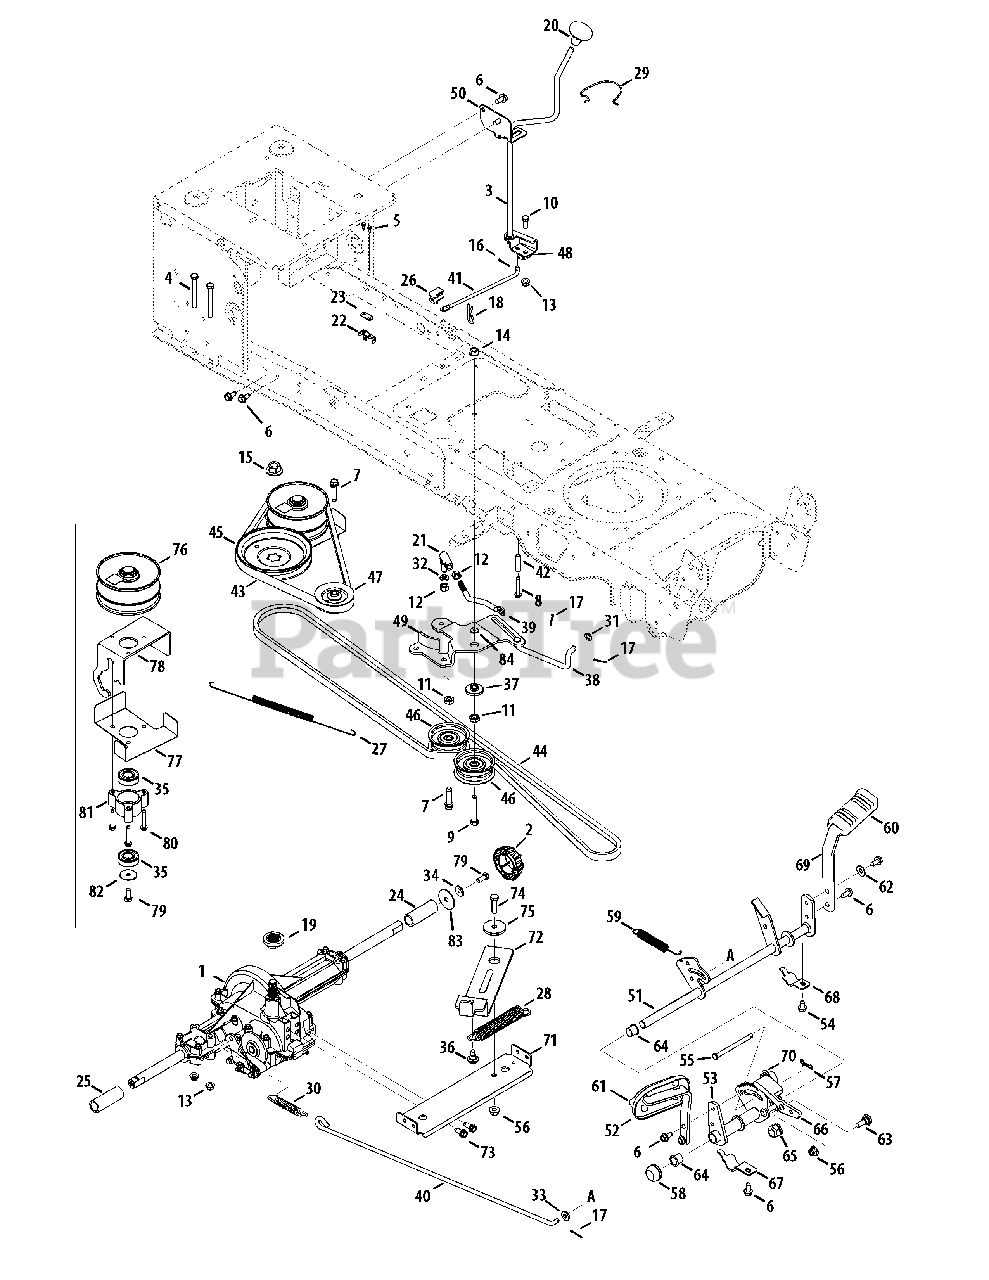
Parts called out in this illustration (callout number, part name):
1	Transaxle Ass’y
2	Hub Cap
3	Shift Lever Ass’y
4	Hex Screw 5/16-18 x 2.75
5	Hex Wash HD AB S-Tapp Screw #8-.50
6	Hex Wash Hd. Tapp Screw. 5/16-18 x .75
7	Hex L-Wash HD Screw 3/8-16 x 1.5
8	Hex TT-Tap Screw 1/4-20 x 1.75
9	Hex Bolt 3/8-16 x 2.25" Lg.
10	Screw-Hex Cap
11	Hex Jam Nut 7/16-20
12	Hex Nut 3/8-24
13	Flange Locknut 5/16-18 Gr. F, Nylon
14	Hex. Flanged L-Nut 3/8-16 Gr. F
15	Flange Nut
16	Int. Cotter Pin .072 x 1.13" Lg.
17	Cotter Pin 3/32 dia x 1.00 Lg.
18	Cotter Pin
19	Hub, 5/8" spline
20	Shift Knob
21	Drag Link Ball Joint
22	Short Spring Switch
23	Insulator Nut Plate
24	Sleeve, .758 x .821 x 3.3125
25	Sleeve, .758 x .821 x 2.4375
26	Shift Plate Bearing
27	Extension Spring .70 OD x 12.0
28	Extension Spring .97 OD x 6.18
29	Complete Spring Clip
30	Extension Spring .59 OD x 4.0
32	L-Wash 3/8 ID
33	Flat Washer .312 ID x .75 OD
34	Cupped Washer .345 ID x .88 OD x .060
35	Ball Bearing 17 x 40 x 12
36	Shoulder Screw 5/16-18, .43 x .29
37	Shoulder Spacer 1.375 x .380 x .183
38	Footpedal By pass Rod
39	Idler adjustment Rod
40	Brake Rod
41	Shift Rod
42	Spacer .260 x .372 x 1.420
43	V-Belt
44	V-Belt
45	Pulley, V-Type, 7.25 dia.
46	Idler Pulley, Flat 2.75 OD
47	Idler Pulley V-Type x 3.06
48	Shift adjustment Bracket
49	Idler Bracket (Centre Double)
50	Shift Bracket F-N-R
51	Brake Control Ass’y
52	AutoDrive Pedal Assembly
53	Pedal Bracket Assembly
54	Self-tapping Screw 5/16-18 x .625
55	Clevis Pin 5/16 x 3.985
56	Flange Lock-Nut 3/8-16 Gr. F Nylon
57	Bow-Tie Cotter Pin
58	Push Cap 5/8" Dia Rod
59	Extension Spring .63 dia. x 4.95
60	Brake Pedal Pad
61	AutoDrive Pedal Pad
62	Cupped Washer .345 ID x .88 OD x .060
63	Shoulder Screw .500 x .25
64	Nyliner Flanged Brg.
66	Cruise Latch
67	Pedal Strap Support Bracket
68	Pedal Strap Support Bracket
69	Brake Pedal Bracket
70	Reinforcement Plate Bracket
71	Transmission Bracket Assembly
72	Idler Bracket Ass’y
73	Hex Wash. Hd. Screw. 5/16-18 x .75 Lg.
74	Hex Bolt 3/8-16 x 1.25
75	Shoulder Spacer .884 x .190
76	Variable Speed Pulley Assembly 4.75 OD
77	Belt Keeper Ass’y
78	Variable Bracket Ass’y
79	Hex L-Bolt 5/16-24 x .75 Gr. 5
80	Hex Wash HD Bolt 1/4-20 x 1.50" Lg.
81	Bearing Cup
82	Flat Washer .22 ID x 1.25
83	Flat Washer, .350 x 1.59 x .062
84	Flat Washer .385 x 1.0 x .03
